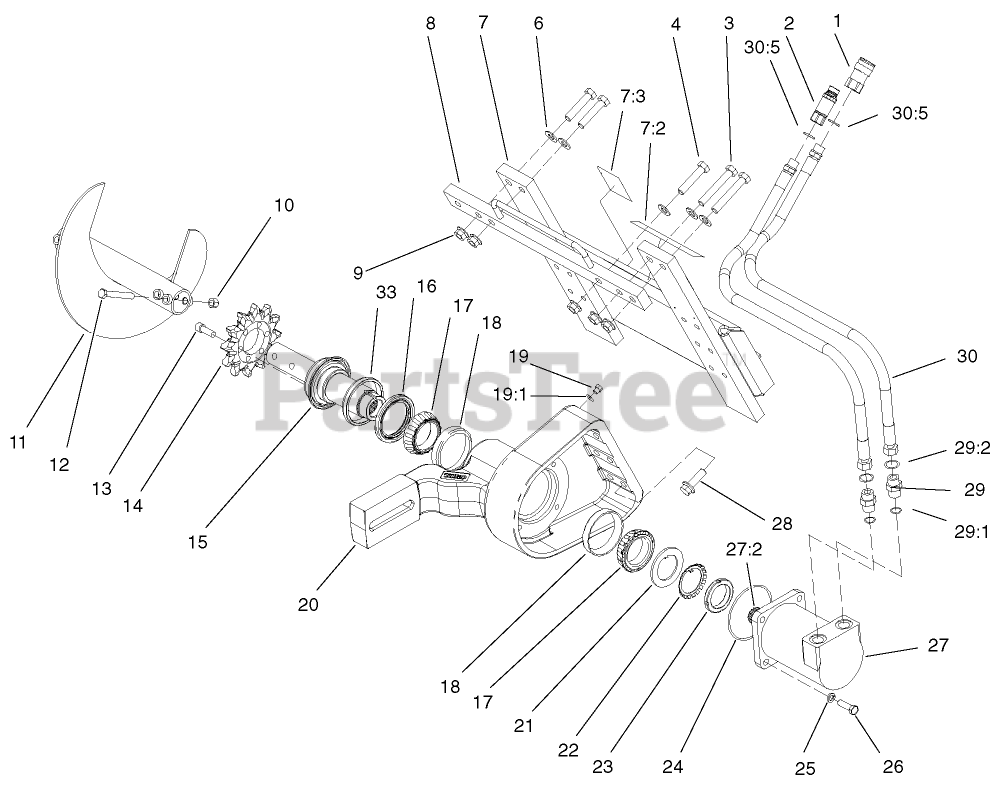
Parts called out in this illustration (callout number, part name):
1	COUPLER-FACE, FLUSH
2	NIPPLE-CONNECT, PRESSURE
3	SCREW-HH
4	SCREW-HH
6	WASHER-FLAT
7	MOUNT ASM
7:2	DECAL-DANGER
7:3	DECAL-DANGER
8	CROSSBAR ASM
9	NUT-FLANGE
10	NUT-LOCK, NI
11	AUGER ASM
12	SCREW-HH
13	SCREW-HSH
14	SPROCKET-TRENCHER
15	SHAFT-TRENCHER
16	SEAL-SHAFT
17	CONE-BEARING
18	CUP-BEARING
19	PLUG ASM
19:1	O-RING
20	Mount-Boom
21	WASHER-TONGUED
22	WASHER-LOCK, BEARING
23	NUT-LOCK, BEARING
24	O-RING
25	WASHER-LOCK
26	SCREW-HH
27	MOTOR-HYD
29	FITTING-STRAIGHT
29:1	O-RING
29:2	O-RING
30	HOSE ASM
30:5	O-RING
33	SPACER
